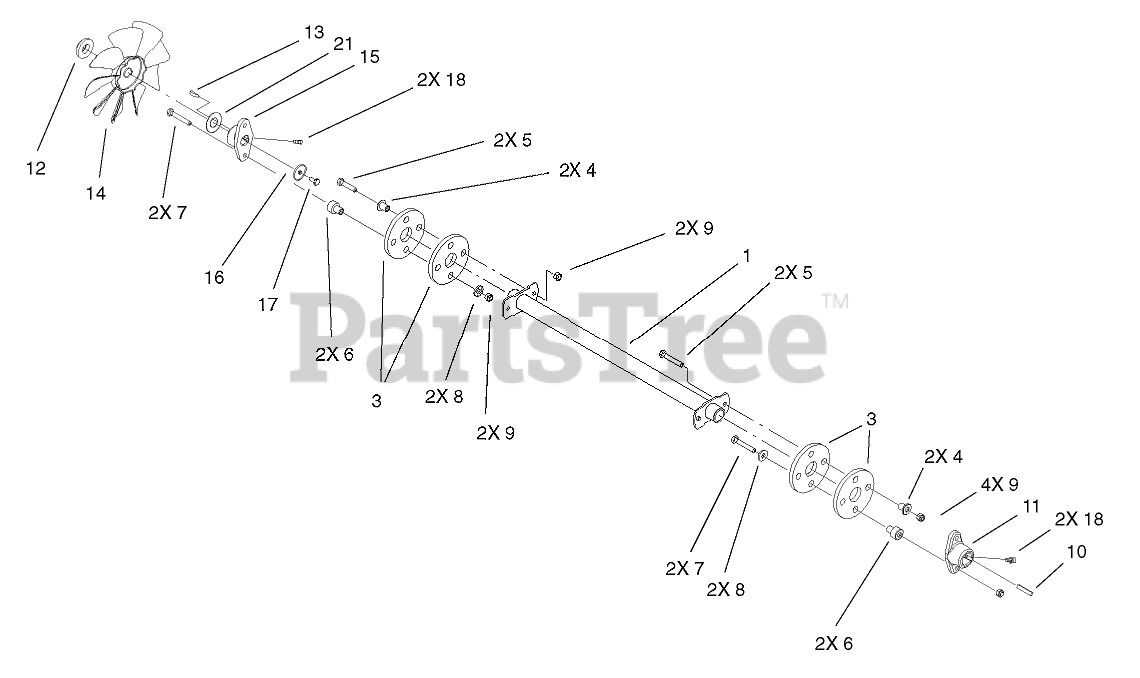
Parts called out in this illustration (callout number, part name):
1	SHAFT-DRIVE
3	COUPLING-RUBBER
4	SPACER
5	SCREW-HH
6	SPACER
7	SCREW-HH
8	WASHER-FLAT
9	NUT-LOCK, NI
10	KEY-SQUARE
12	SPACER-FAN
13	KEY-WOODRUFF
14	FAN-HYDRO
16	WASHER
17	SCREW-HH
18	SCREW-SET
21	WASHER - FAN
